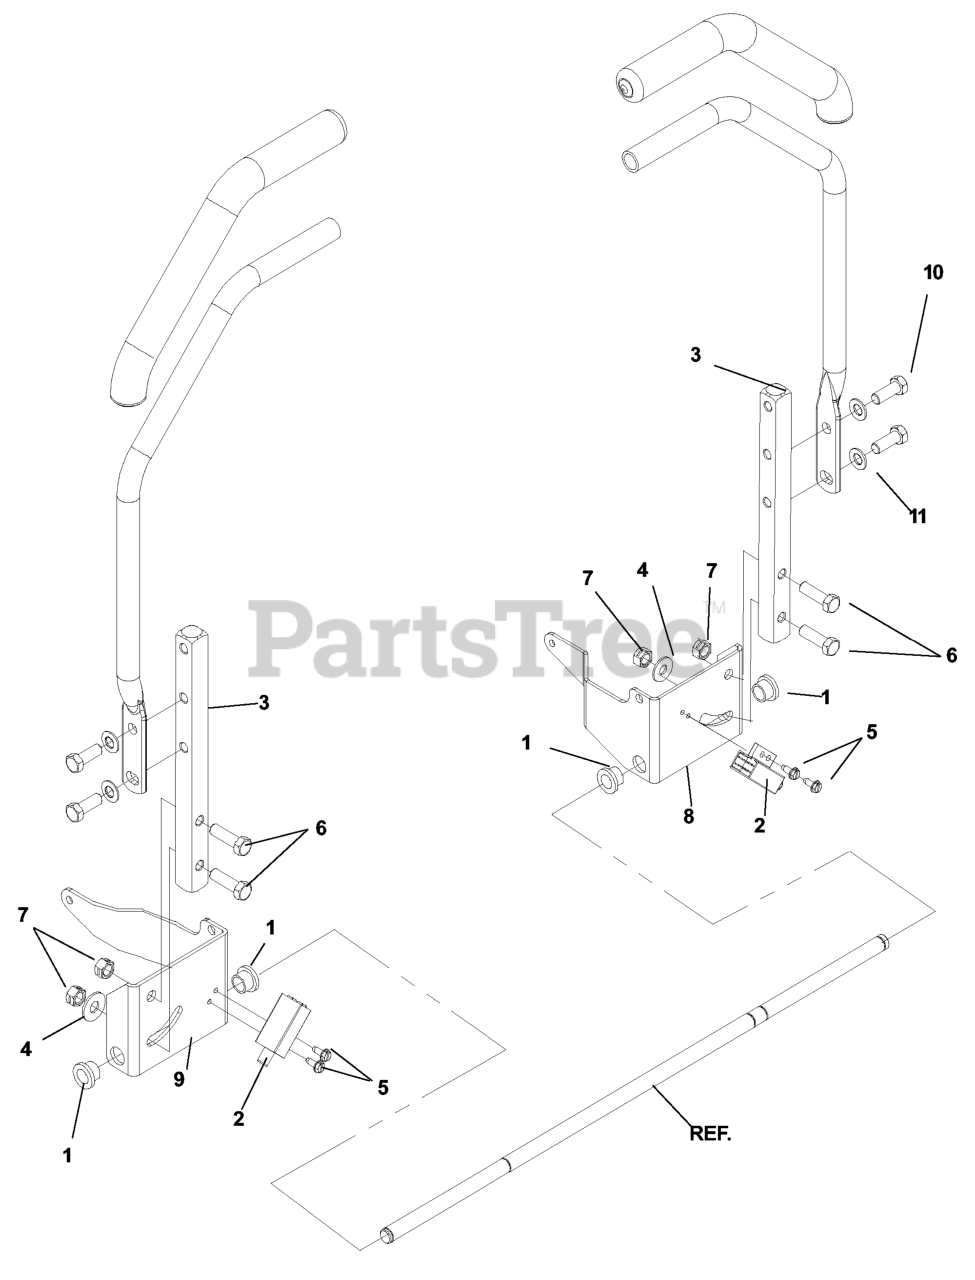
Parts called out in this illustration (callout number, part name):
1	BUSHING, FLANGED NYLON
2	SWITCH, INTERLOCK
3	CONTROL ARM
4	WASHER 3/8 FLAT
5	SCREW #10 X 1/2 SELF TAPPING
6	TAP BOLT 3/8C X 1.5
7	NUT 3/8C CENTERBLOCK
8	CONTROL BRKT-LH
9	CONTROL BRKT-RH
10	HCS 3/8-16X1.GRD.5.ZD
11	WASHER, 3/8 DISC SPRING SPEC
